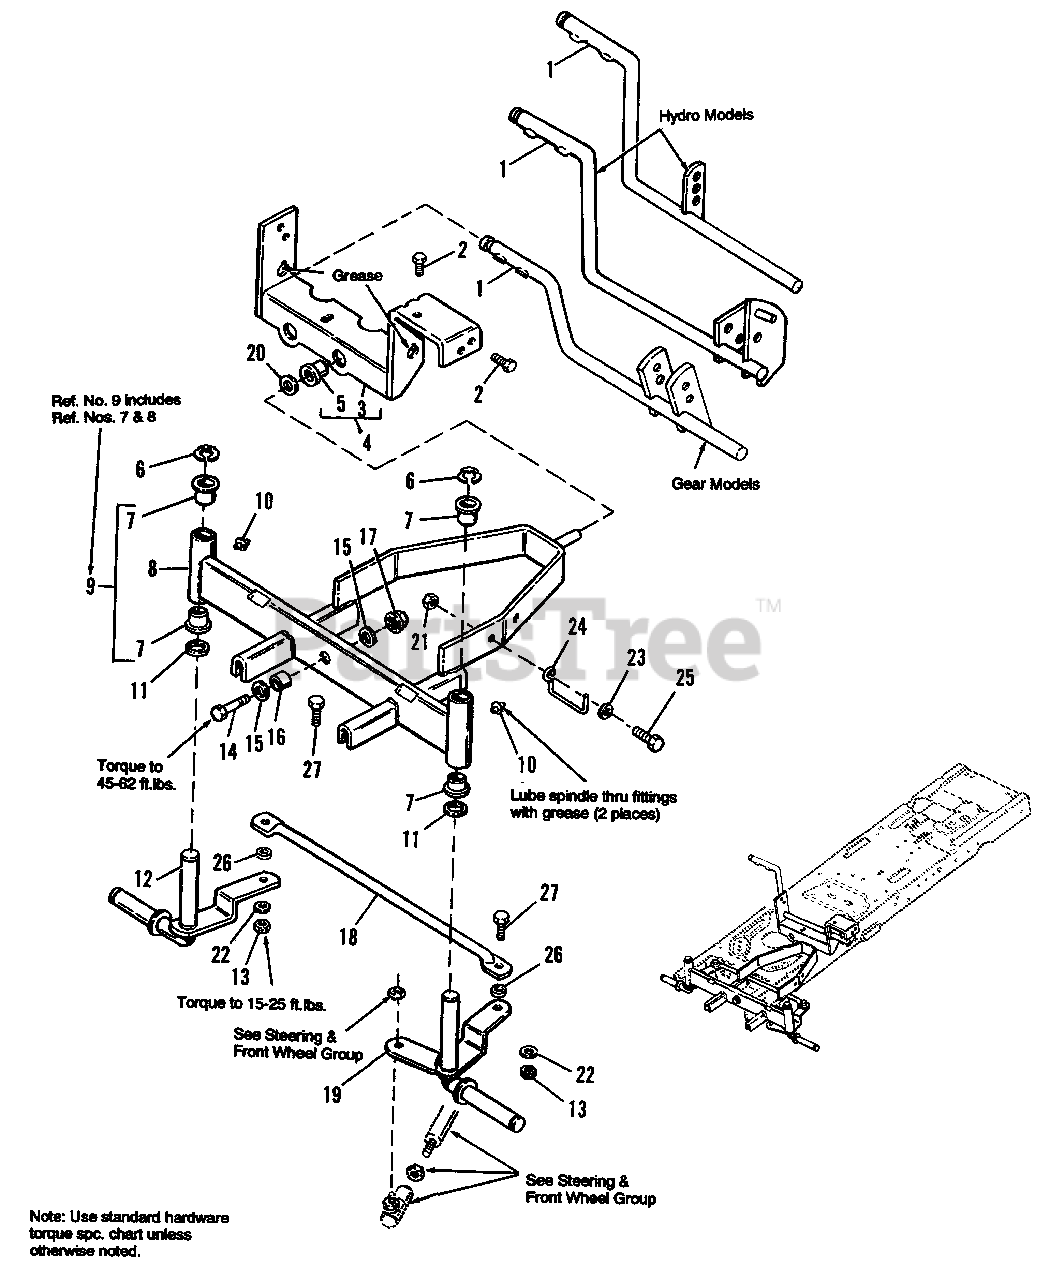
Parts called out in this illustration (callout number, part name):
1	LEVER ASSY., Brake (Gear Models, Mfg. Nos. 1692160, 1692166)
1	LEVER ASSY., Brake (Hydro Models, Mfg. Nos. 1692156, 1692164)
2	SCREW, Taptite, 5/16-18 x 3/4
4	SUPPORT ASSY., Rear (Incl. Ref. No. 5)
6	KLIPRING, Ext., 3/4
9	AXLE ASSY., Front (Incl. Ref. Nos. 7 & 8)
10	FITTING, Lube, Drive Type
11	WASHER
12	SPINDLE ASSY., R.H.
13	LOCKNUT, Hex, 3/8-16
14	CAPSCREW, Hex, 1/2-13 x 1-3/4 (Gr. 8)
15	WASHER
16	SPACER
17	LOCKNUT, Hex, Flange Lock, 1/2-13
18	TIE ROD ASSY.
19	SPINDLE ASSY., L.H.
21	NUT, Hex, 5/16-18
22	WASHER, 3/8
24	GUIDE, Drag Link
25	CAPSCREW, Hex Hd., 5/16-18 x 1
27	CAPSCREW, 3/8-16 x 1
